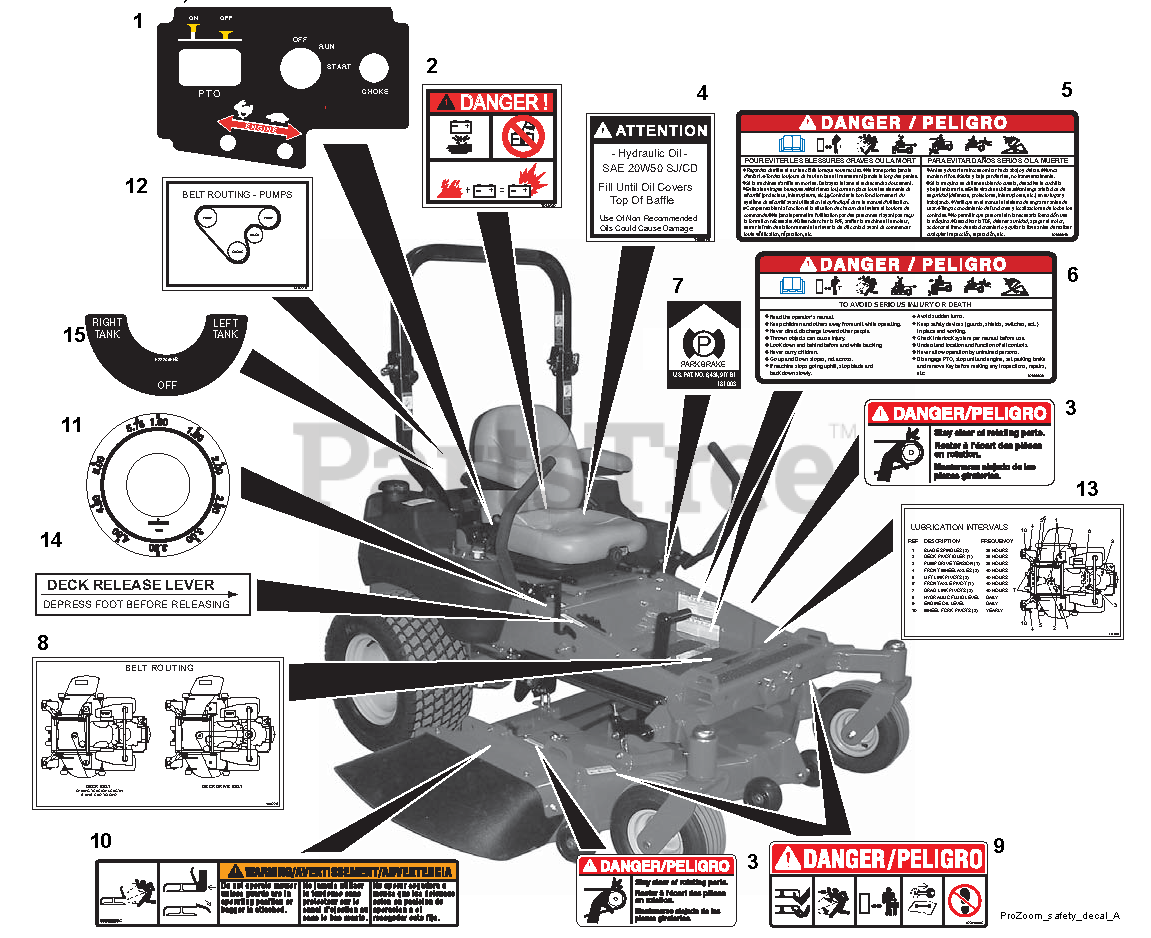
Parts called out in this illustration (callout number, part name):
1	DECAL, CONTROL PANEL
2	DECAL, DANGER - BATTERY
3	DECAL-DANGER-BELT ROTATING
4	DECAL, ATTENTION HYD. RES.
5	DECAL, SAFETY FRENCH - SPANISH
6	DECAL, SAFETY ENGLISH
7	DECAL, PARK BRAKE
8	DECAL, BELT ROUTING
9	DECAL, MOWER PAN DANGER
10	DECAL, WARNING
11	DECAL, HOC INCREMENT
12	DECAL, PUMP BELTS
13	DECAL, LUBRICATION INTERVALS
14	MANUAL, EVERRIDE WARRIOR
15	DECAL- FUEL CONTROL VALVE
